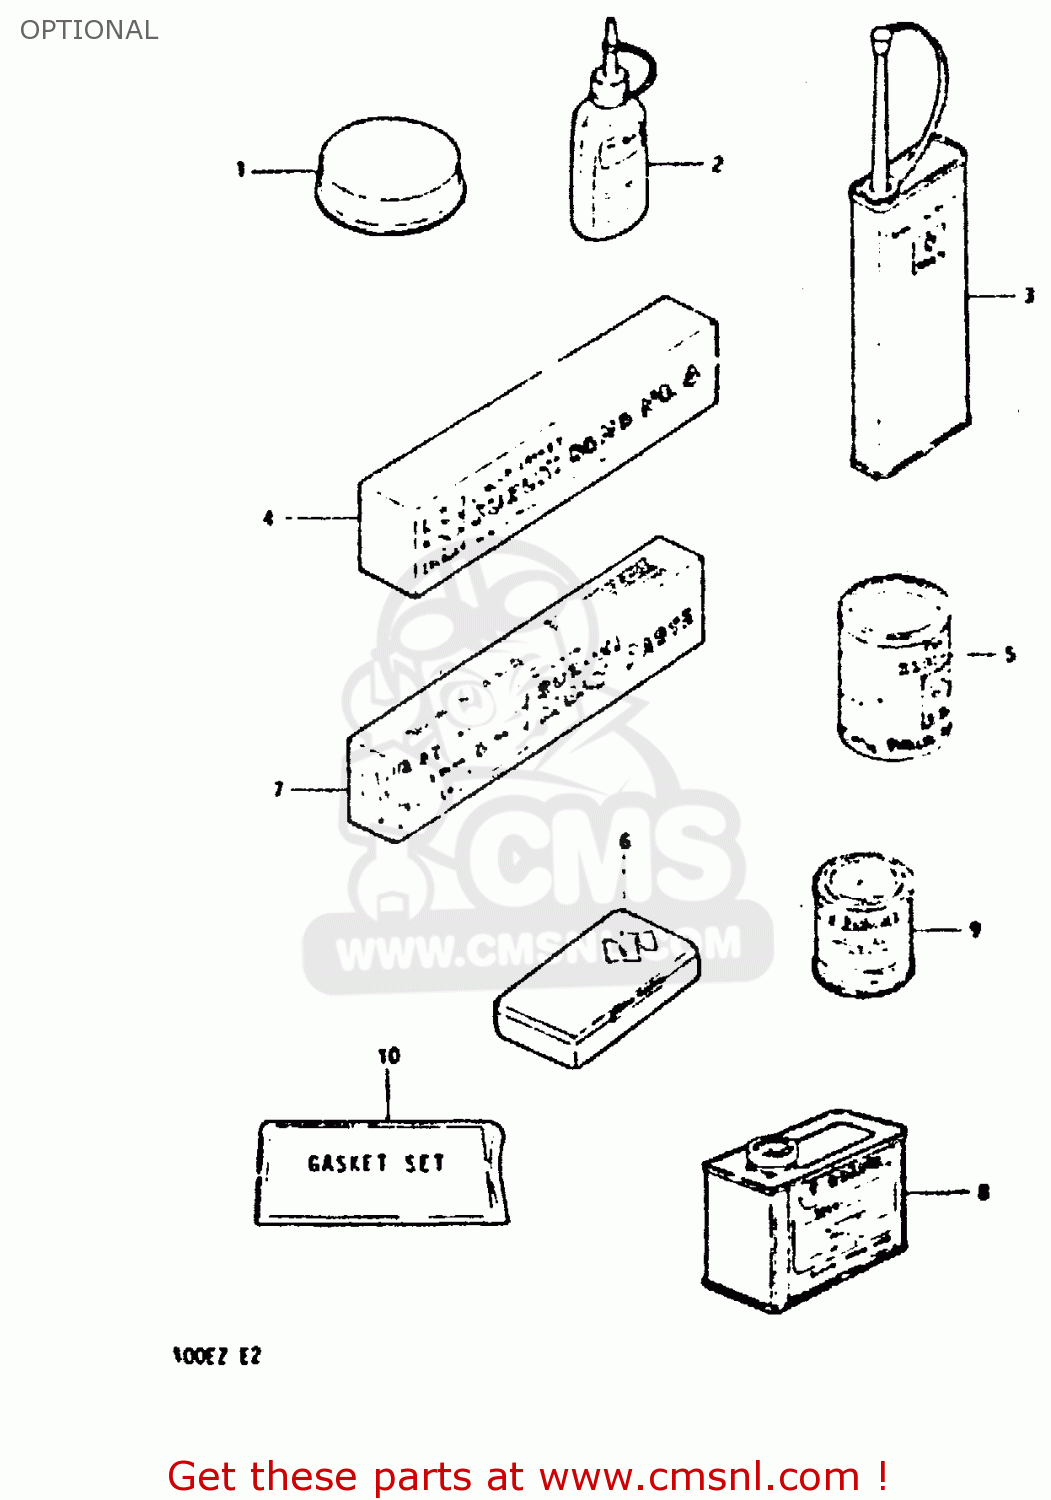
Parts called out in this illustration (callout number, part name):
1	GREASE,PBC FOR BRK PAD 20G
2	THREAD LOCK NO.1342
3	THREAD LOCK NO.1401 CLEAR 200G
4	BOND 1104
5	GREASE(C)EP2 LITHIUM 150G
6	TUBE REPARING TOOL
7	SUZUKI MOLY PASTE
8	PAINT (BLACK)
9	PAINT,BLACK
10	GASKET SET
